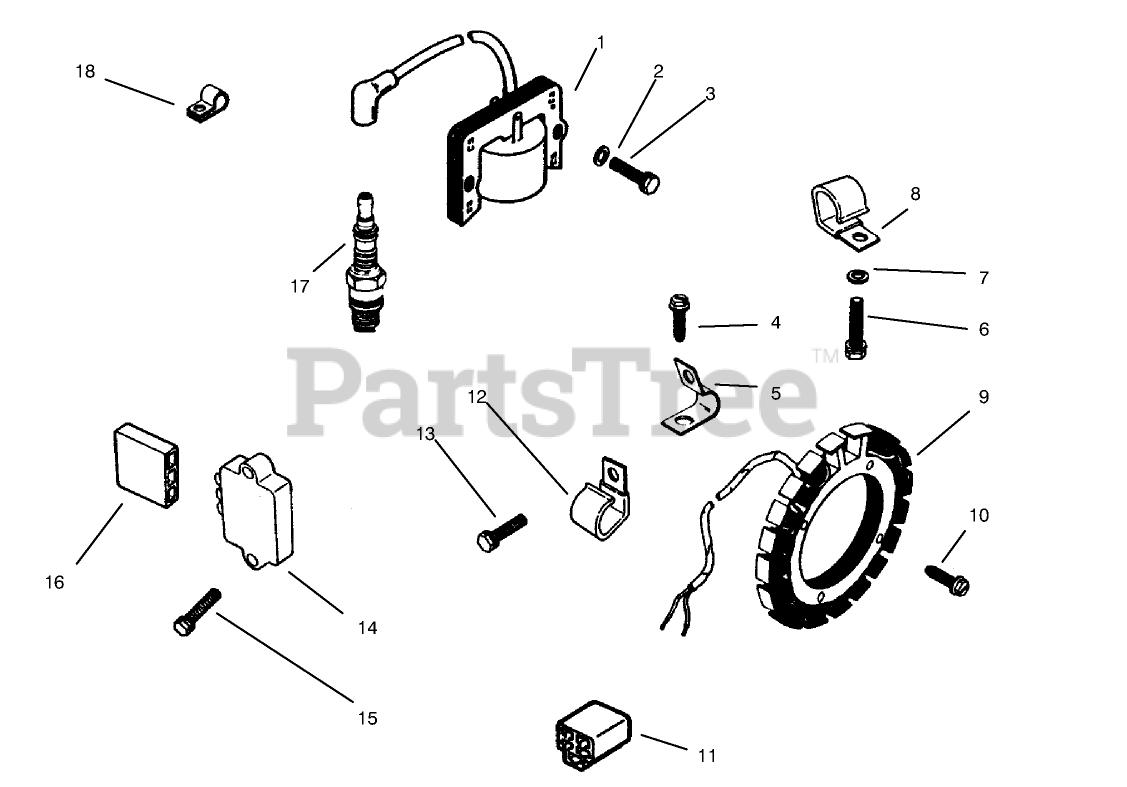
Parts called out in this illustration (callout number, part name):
1	Module-Ignition
2	Washer
3	Screw
4	Screw-Hex Hd
6	Screw
7	Washer
9	Stator
10	Screw
11	Connector
12	CLIP
13	SCREW-HH
14	Kit-Rectifier/Regulator (Incl. Ref. #2)
14	Regulator-Recifier
15	Screw
16	Connector
17	Plug-Spark
18	Clip-Cable
